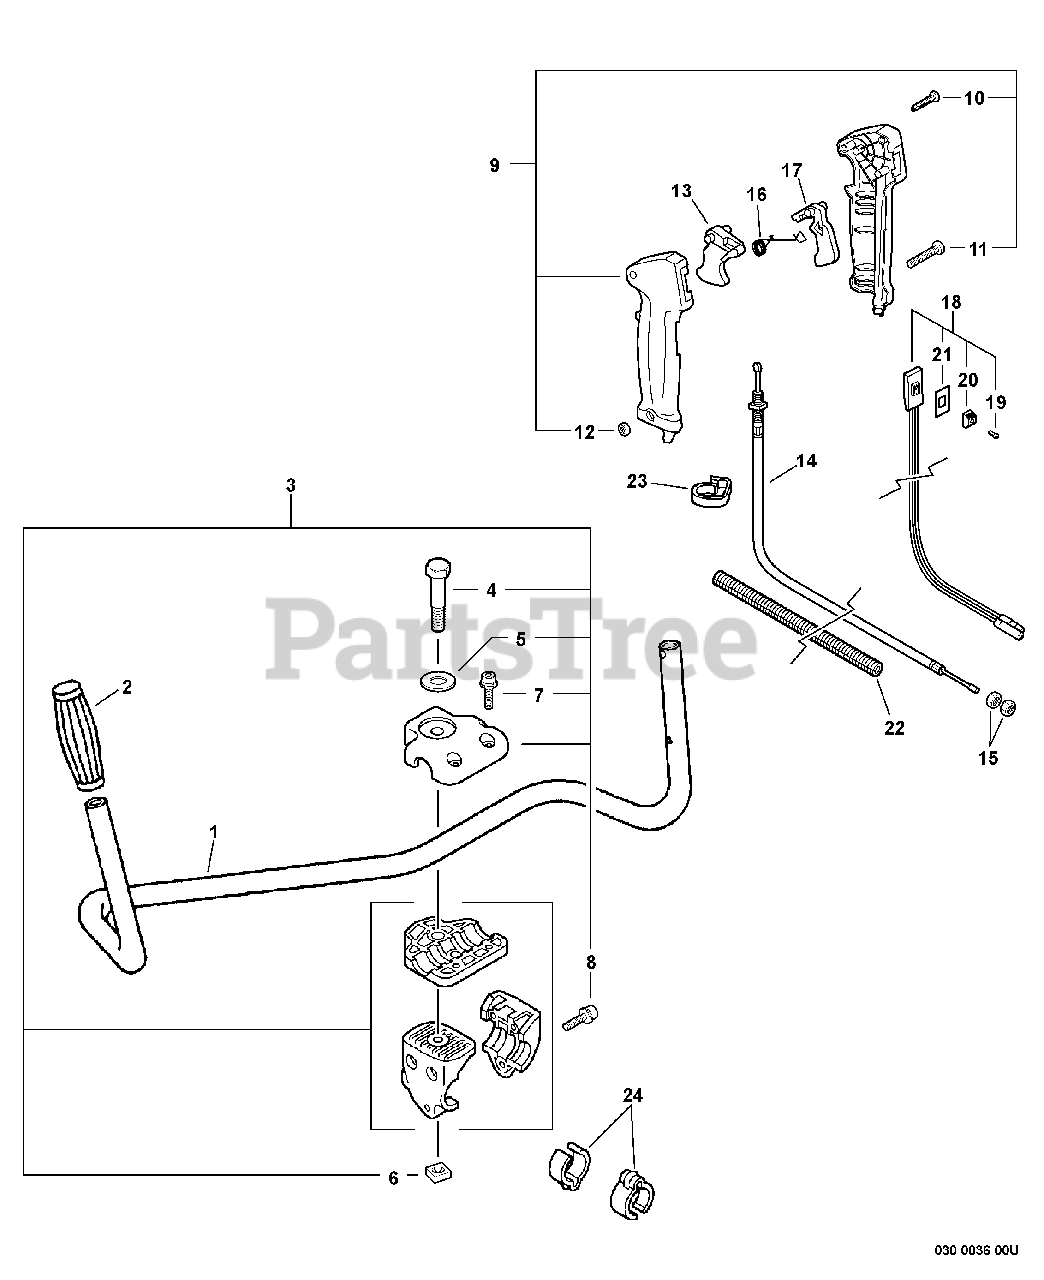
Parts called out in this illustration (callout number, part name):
1	HANDLE - FRONT
2	GRIP, HANDLE - LEFT
3	HANDLE BRACKET KIT
4	BOLT - 8X55
5	WASHER - 8
7	SCREW - 5X20
8	SCREW - 5X30
9	THROTTLE CONTROL ASSY
10	SCREW - 3X25
11	SCREW - 5X30
13	TRIGGER, THROTTLE
14	CABLE, THROTTLE
16	SPRING, LOCKOUT LEVER
17	LOCKOUT, THROTTLE
18	SWITCH, IGNITION
19	SCREW - 3X10
20	KNOB, SWITCH - ORANGE
21	COVER, SWITCH - STOP
22	TUBE, PROTECTIVE - CORRUGATED
